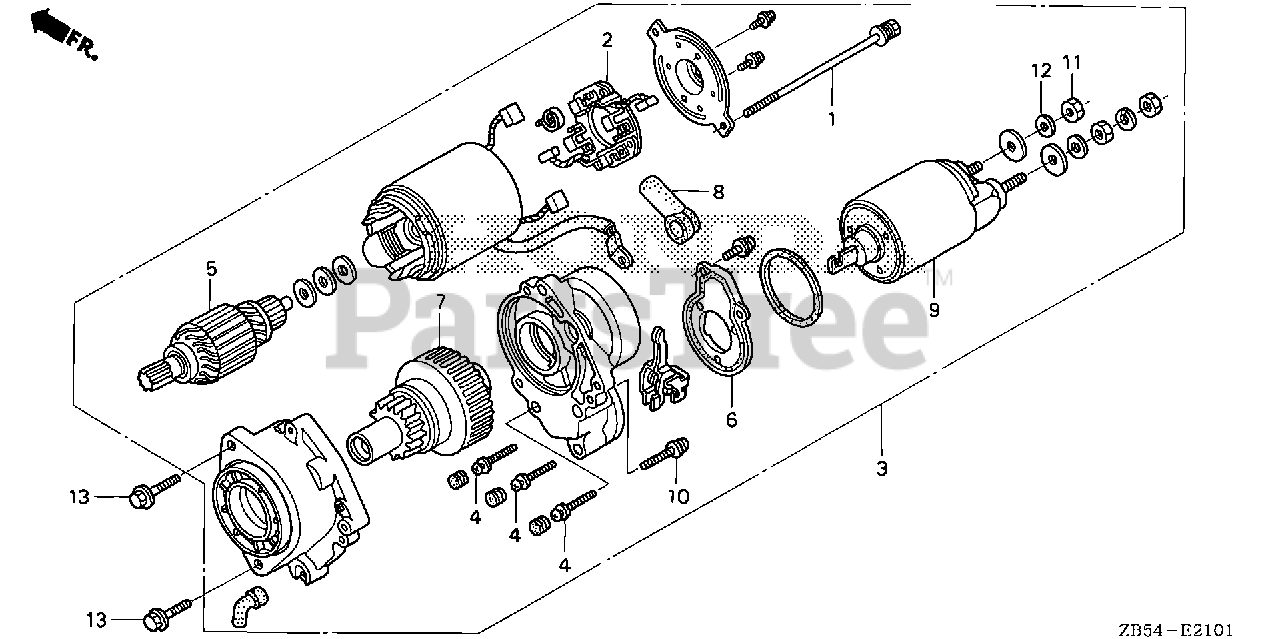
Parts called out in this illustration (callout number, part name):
1	BOLT, SETTING
2	STAY ASSY., BRUSH (N/A FOR USA: SEE ASSEMBLY)
3	STARTER MOTOR ASSY.
4	SCREW-WASHER (4X28) (MITSUBA)
5	ARMATURE ASSY.
6	PLATE, FR.
7	GEAR ASSY.
8	COVER, TERMINAL
9	SWITCH ASSY.
10	SCREW-WASHER (6X25)
11	NUT, HEX. (8MM)
12	WASHER, SPRING (8MM)
13	BOLT, FLANGE (8X20) Use up to Engine SN 1609606.
